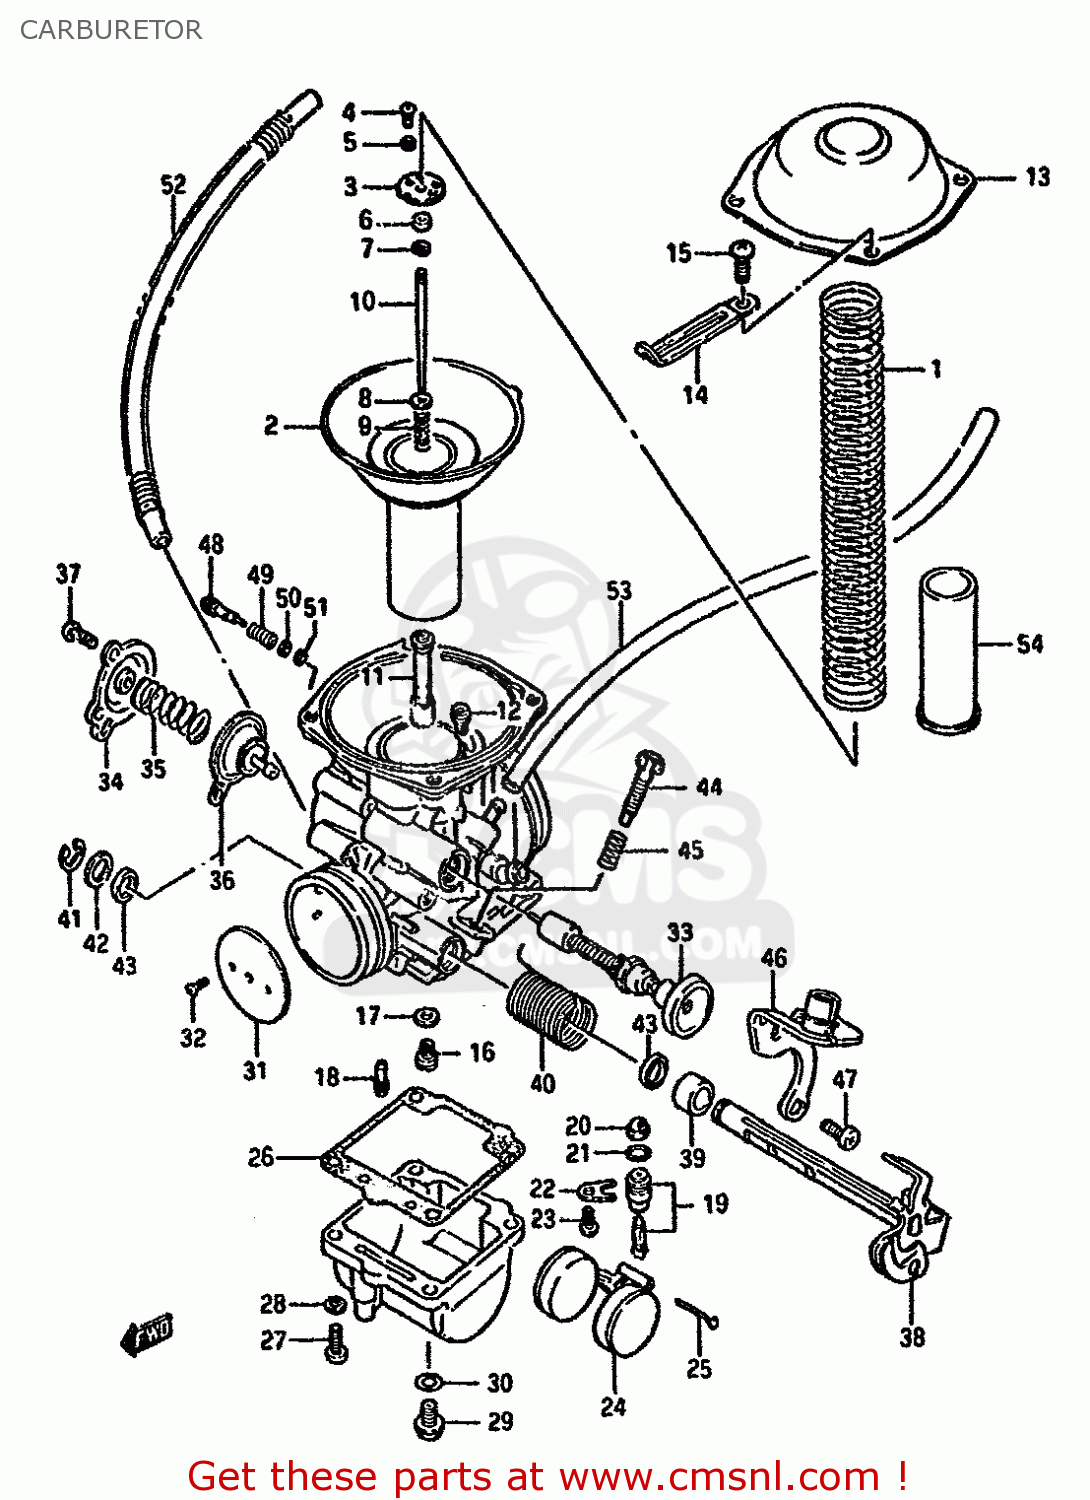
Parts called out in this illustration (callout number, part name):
1	SPRING
2	DIAPHRAGM ASSY
3	PLATE
4	SCREW
5	LOCK WASHER
6	RING
7	CLIP,NEEDLE
8	WASHER
9	SPRING
10	NEEDLE,JET
11	JET,NEEDLE(X-7)
12	JET,PILOT AIR(70)
13	COVER
14	CLIP
15	SCREW 5X10
16	JET,MAIN(130)
17	WASHER,NEEDLE NOZZLE
18	JET,PILOT(47.5)
19	VALVE ASSEMBLY,NEEDLE
20	FILTER
21	O-RING,NEEDLE VALVE
22	PLATE
23	SCREW
24	FLOAT
25	PIN,FLOAT
26	GASKET (NA)
27	SCREW
28	LOCK WASHER
29	PLUG,DRAIN
30	GASKET (NAS)
31	VALVE,THROTTLE (BUTTERFLY)
32	SCREW
33	PLUNGER ASSEMBLY
34	COVER
35	SPRING
36	DIAPHRAGM ASSY
37	SCREWM4X0.7X10
38	SHAFT ASSEMBLY,THROTTLE
39	RING
40	SPRING
41	E RING
42	GASKET,THROTTLE SHAFT (NAS)
43	SEAL
44	SCREW,THROTTLE STOP
45	SPRING
46	BRACKET ASSY
47	SCREW
48	SCREW,PILOT AIR
49	SPRING
50	WASHER
51	O RING,PILOT AIR SCREW
52	HOSE ASSEMBLY
53	HOSE
54	PIPE
